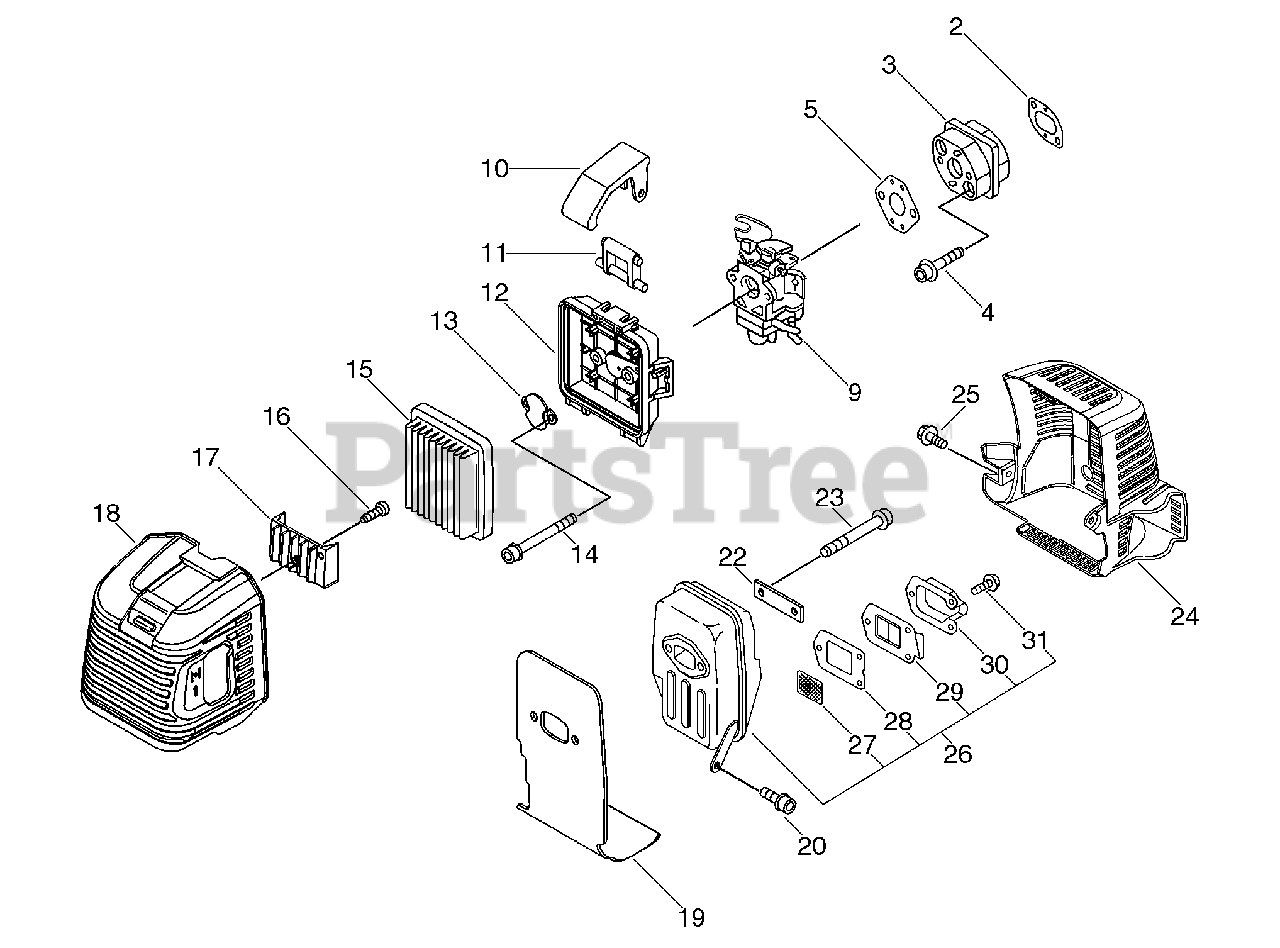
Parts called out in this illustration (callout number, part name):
2	GASKET, INTAKE
3	INSULATOR, INTAKE
4	BOLT 5×25
5	GASKET, INTAKE
9	CARBURETOR
10	LATCH, FILTER COVER
12	CASE, AIR FILTER
13	PLATE, PREVENT
14	BOLT 5×55
15	FILTER, AIR
16	SCREW 4×8
17	PIECE, COVER
18	COVER, AIR FILTER
19	HEAT SHIELD, EXHAUST
20	BOLT 5×12
22	PLATE, EYE
23	BOLT 6×60
24	COVER, EXHAUST
25	BOLT 5×12
26	MUFFLER ASSY
27	SCREEN, SPARK ARRESTER
28	GASKET, EXHAUST
29	GUIDE, EXHAUST
30	OUTLET, EXHAUST
31	SCREW 4×10
